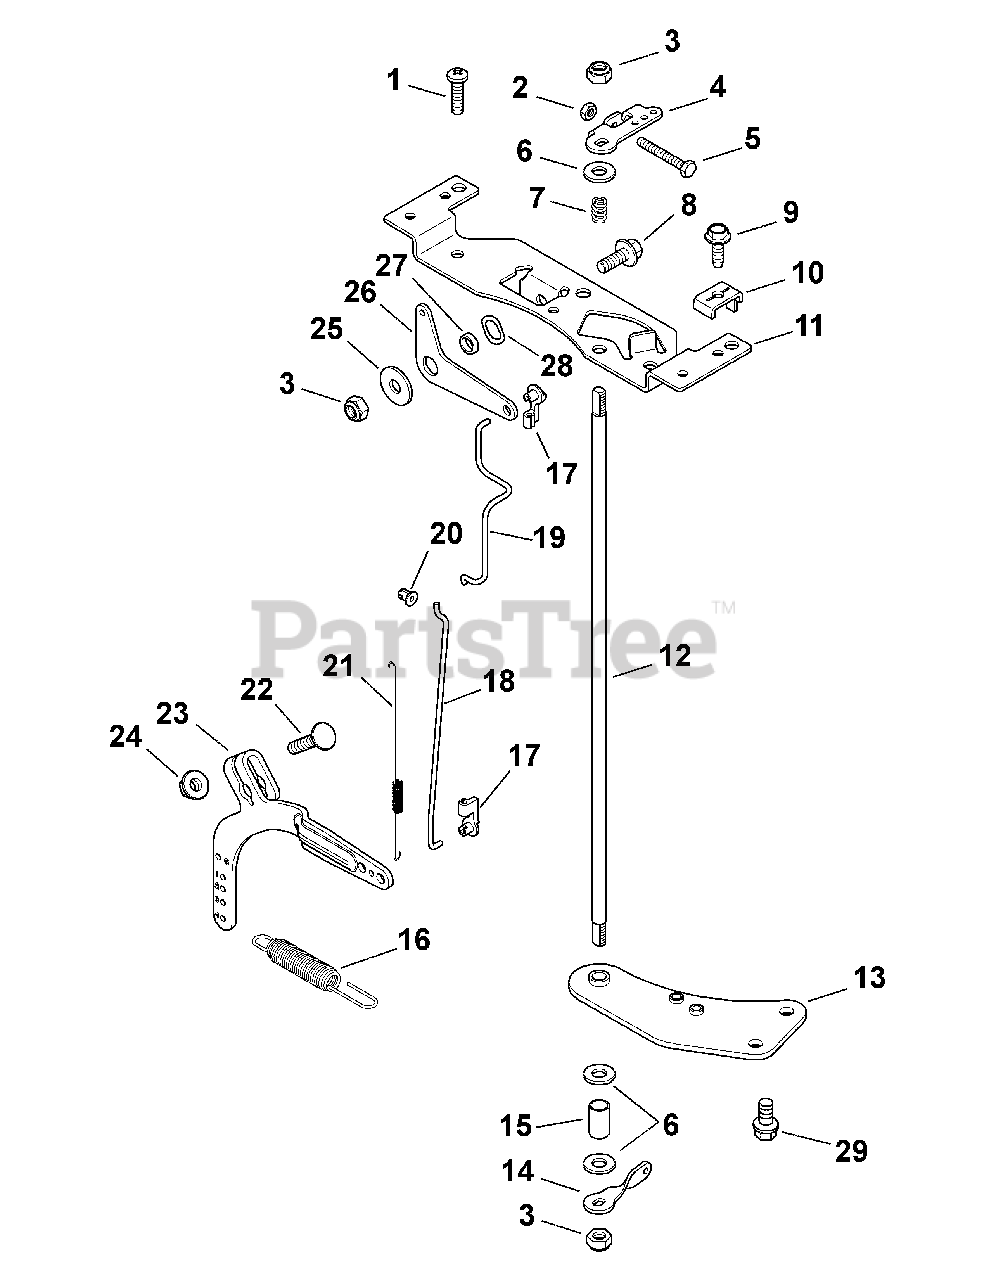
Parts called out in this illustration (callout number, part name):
1	Screw, Phl Hd 11-16 x 3/4"
2	Nut, M4 x 0.7
3	Nut, Lock M6 x 1.0
4	Lever, Throttle Control
5	Screw, Cap M4 x 0.7 x 30
6	Washer, Flat 1/4"
7	Spring, Throttle Shaft
8	Screw, Flg M6x1.0x16
9	Screw, Flg Thd Frm M5 x 0.8 x 16
10	Clamp, Cable
11	Bracket, Control
12	Shaft, Throttle
13	Bracket, Throttle Shaft
14	Lever, Throttle Control
16	Spring, Governor
17	Bushing, Throttle Linkage
18	Linkage, Throttle
19	Linkage, Choke
20	Bushing, Linkage Retaining
21	Spring, Linkage
22	Bolt, Rd Hd Sq Neck M6x1.0x25
23	Lever, Governor
24	Nut, FLG M6 x 1.0
25	Washer, Flat 1/4"
26	Lever, Choke
28	Washer, Spring 3/8"
29	Screw, Flg Thd Frm M6 x 1.0 x16
